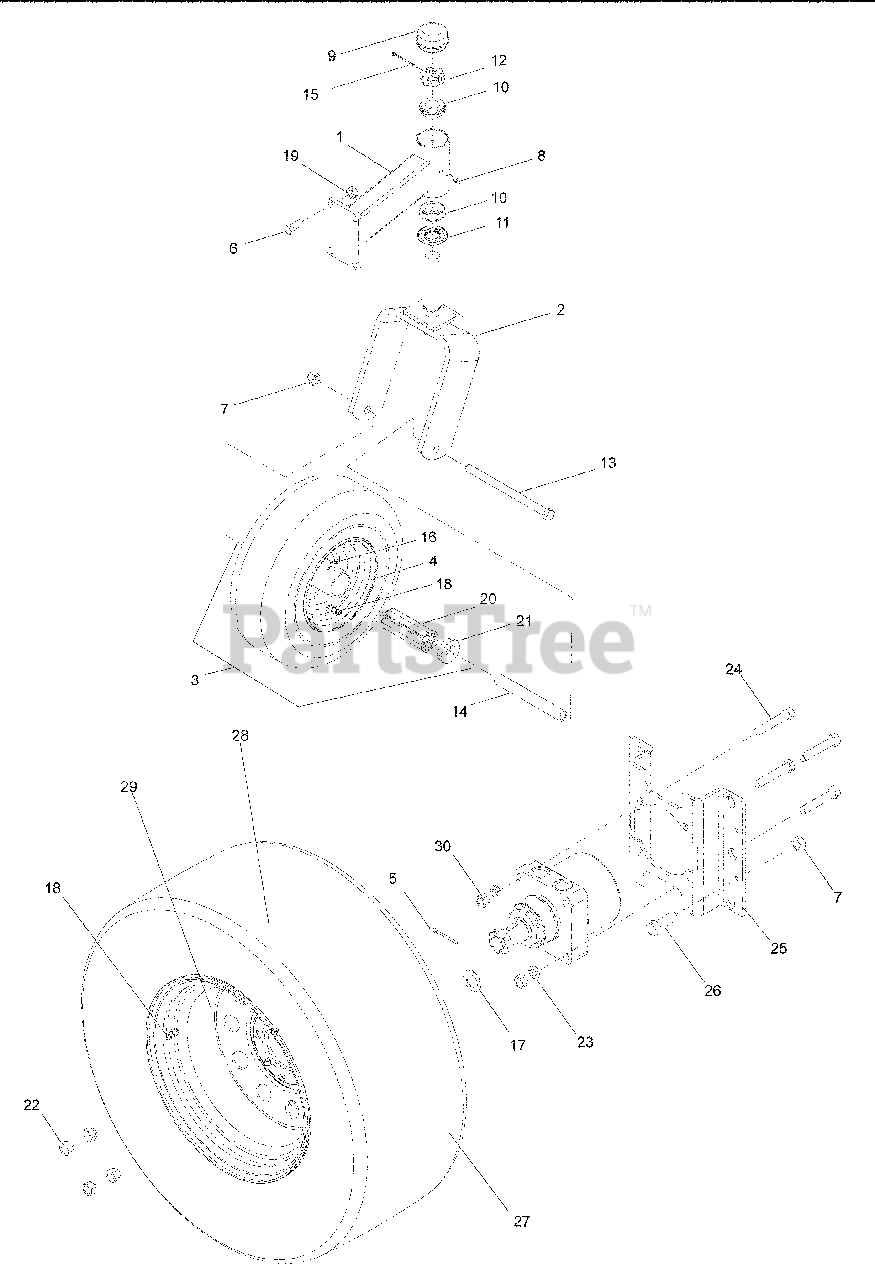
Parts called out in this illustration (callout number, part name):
1	CASTER ARM
2	CASTER YOKE
4	RIM
5	COTTER PIN
6	HCS 7/16-14 x 1
7	NUT ½-13 HEX NYLOC
9	CAP, GREASE
10	BEARING, TAPERED
12	NUT 1-14 JAM SPEC
13	HCS ½-13 x 7½
15	PIN, COTTER, 1/8 x 2
17	BUSHING, 1"
18	VALVE STEM
19	NUT 7/16-14 HEX CTRLK GR A
20	BEARING, ROLLER 2½
21	BEARING, FLANGED
23	LOCKWASHER ½
24	HCS ½-13 x 2¾
25	MOTOR STANDOFF
26	HCS ½-13 x 1¼
27	TIRE ASSEMBLY iZ4821, iZ5223 VAN, iZC5223, iZC5221
28	TIRE iZ4821, iZ5223 VAN, iZC5223, iZC5221
29	RIM MODELS iZ4821, iZ5223VAN, i5223
30	NUT ½-13 HEX
